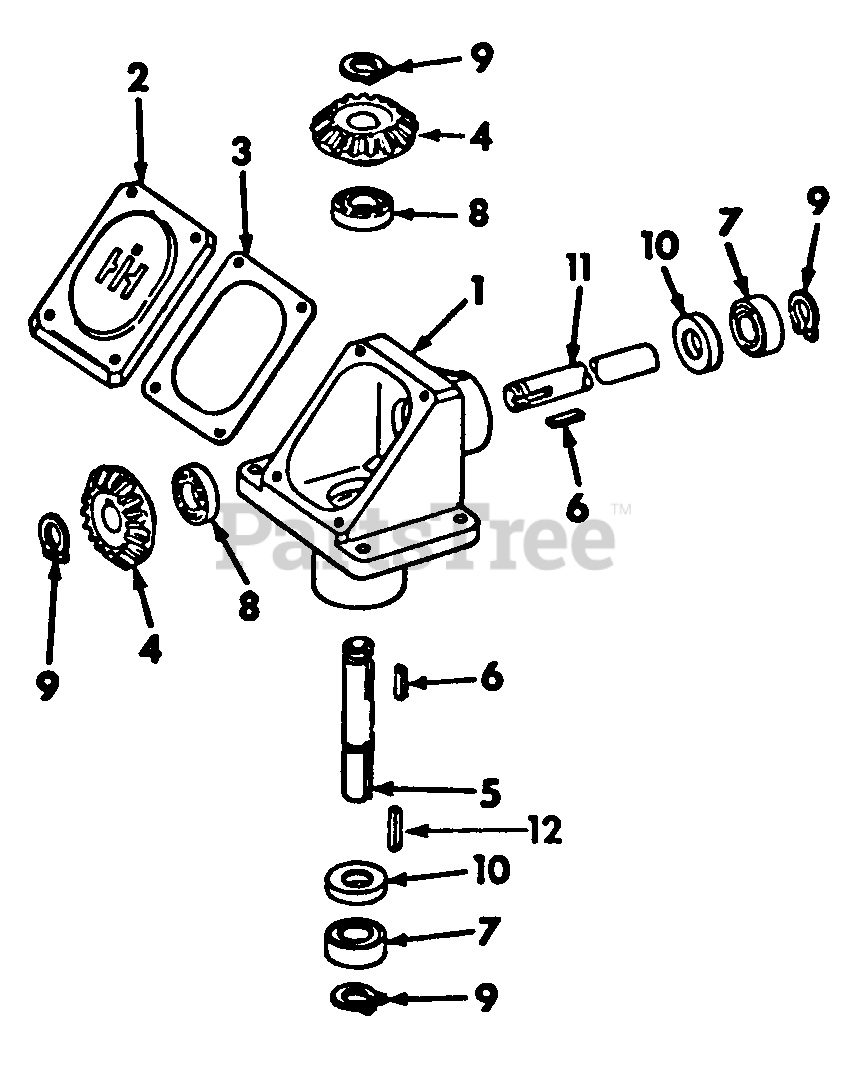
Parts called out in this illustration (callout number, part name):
1	Housing, Gear Box
2	Plate, Cover
3	Gasket, Cover Plate
4	Gear, Miter - 25T
6	Key, 3/16 X 11/16 Sq
7	Bearing, Ball
8	Bearing, Ball
9	Ring, Retaining
12	Key, 3/16 X 1 In. Parallel
